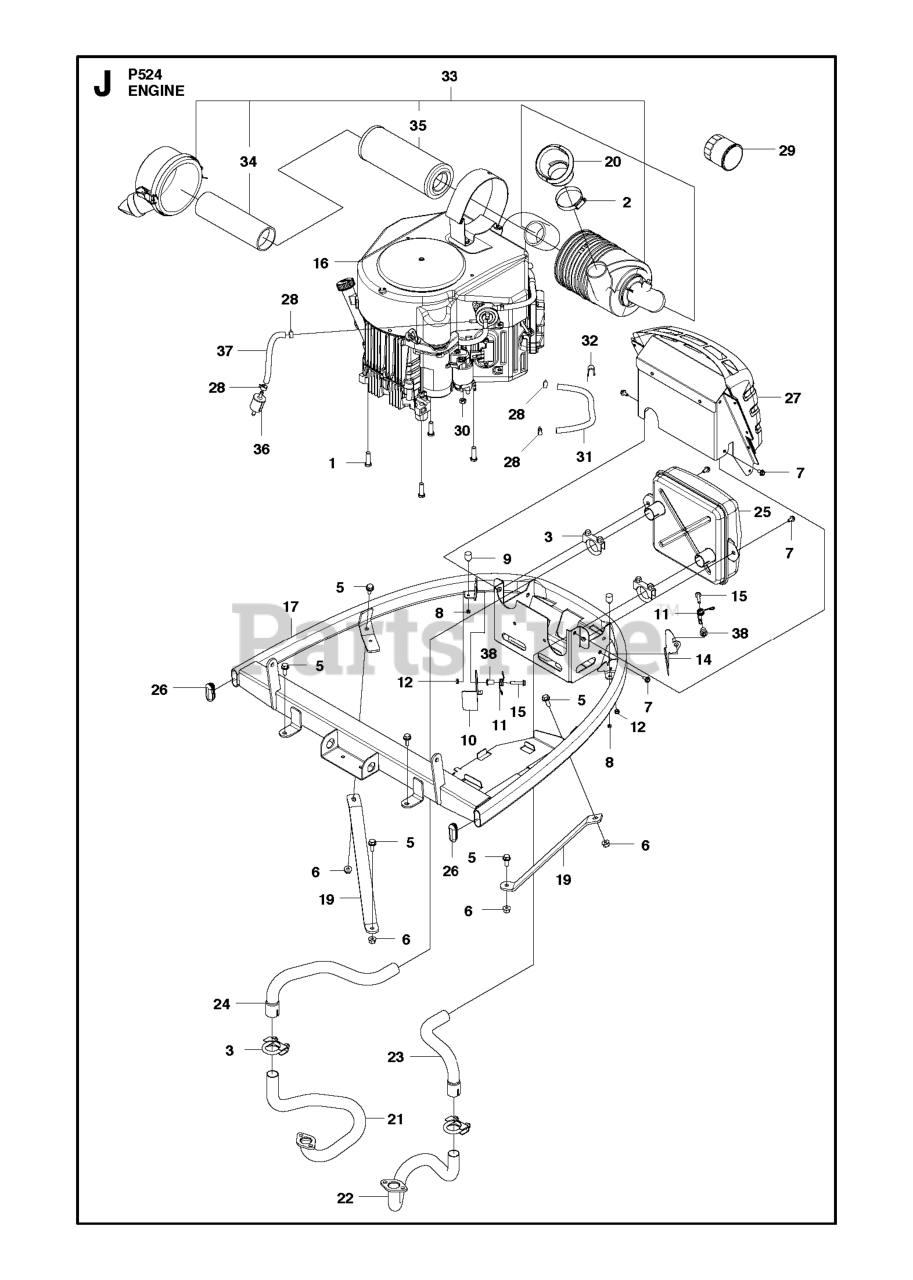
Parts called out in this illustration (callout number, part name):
3	CLAMP
5	SCREW EHHFM
6	NUT FLANGE
7	BOLT
8	LOCKNUT M5
12	LOCKNUT M6
29	OIL FILTERS
30	NUT
32	HOSE CLAMP
